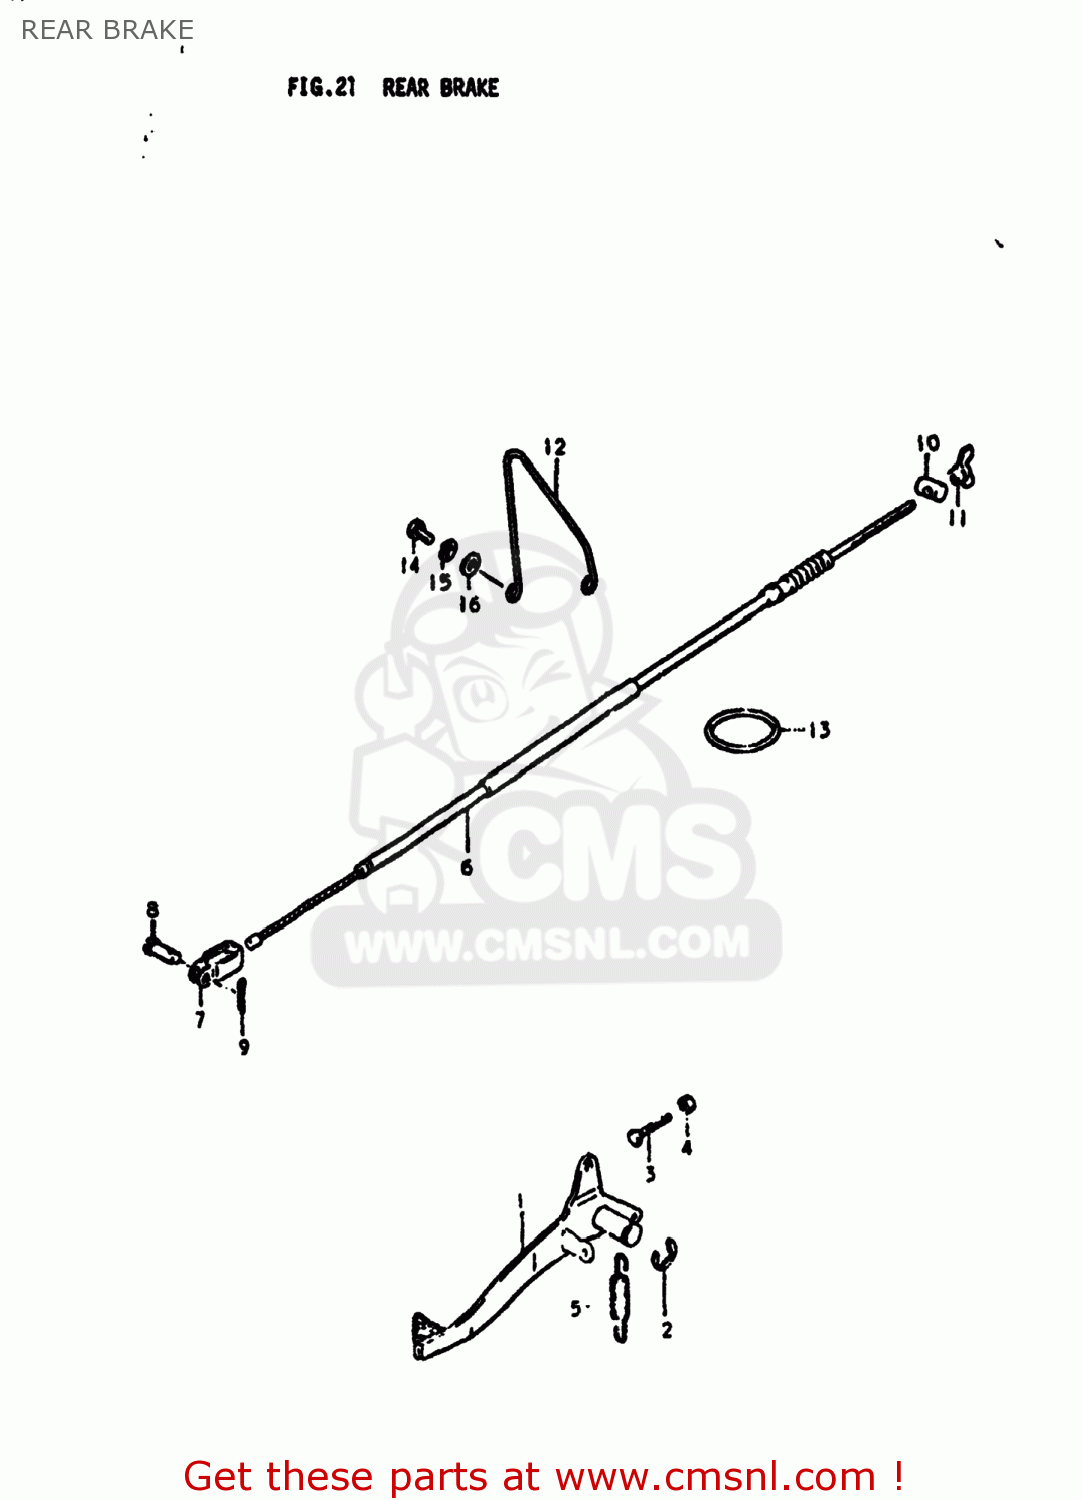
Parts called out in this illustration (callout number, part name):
1	PEDAL,BRAKE
2	E RING
3	BOLT(6X25)
4	NUT
5	SPRING
6	CABLE ASSEMBLY,REAR BRAKE
7	HOOK,REAR BRAKE PEDAL
8	PIN(L:13)
9	PIN
10	PIN(11X18)
11	NUT
12	GUIDE,CABLE
13	O RING,RR BRAKE CABLE
14	BOLT
15	LOCK WASHER
16	WASHER
